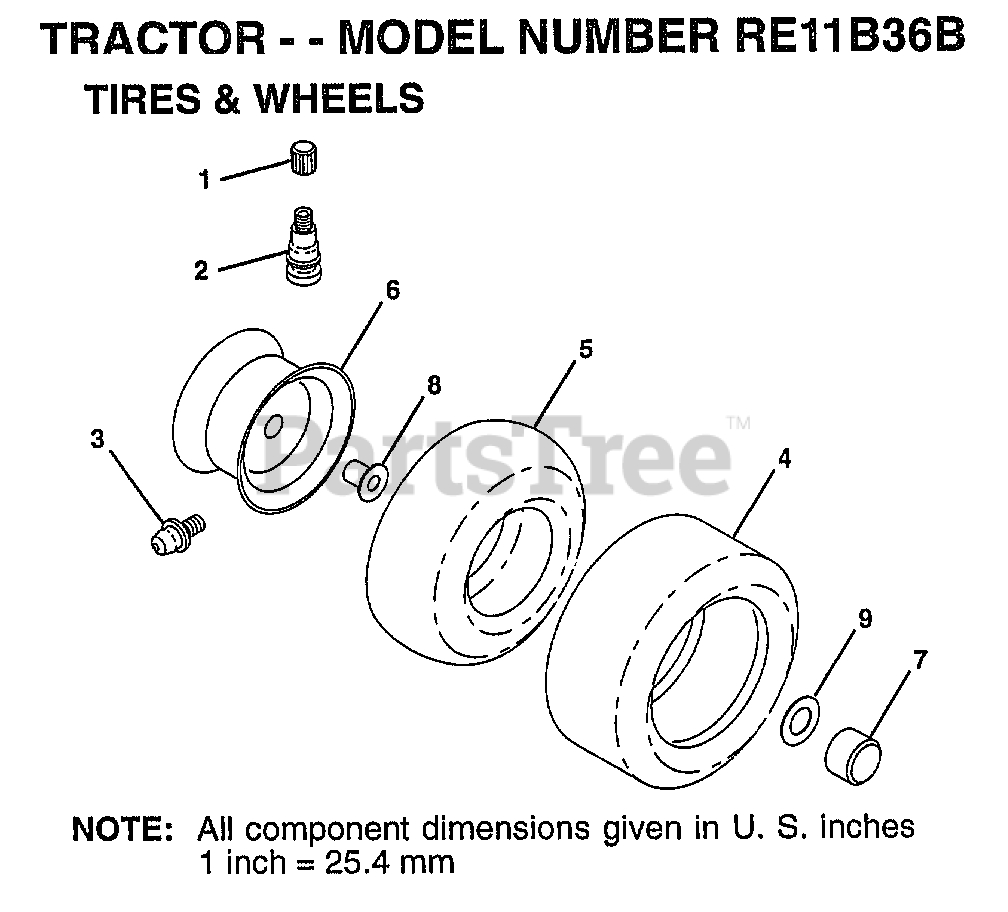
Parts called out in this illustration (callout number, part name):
1	VALVE CAP
2	VALVE STEM LT
3	FITTING LT
4	TIRE FRONT
5	TUBE.5.3/4.5/6
5	TUBE.16X6.5/7.5-8
7	HUB CAP
8	"FLANGE, BEARING"
9	WASHER
